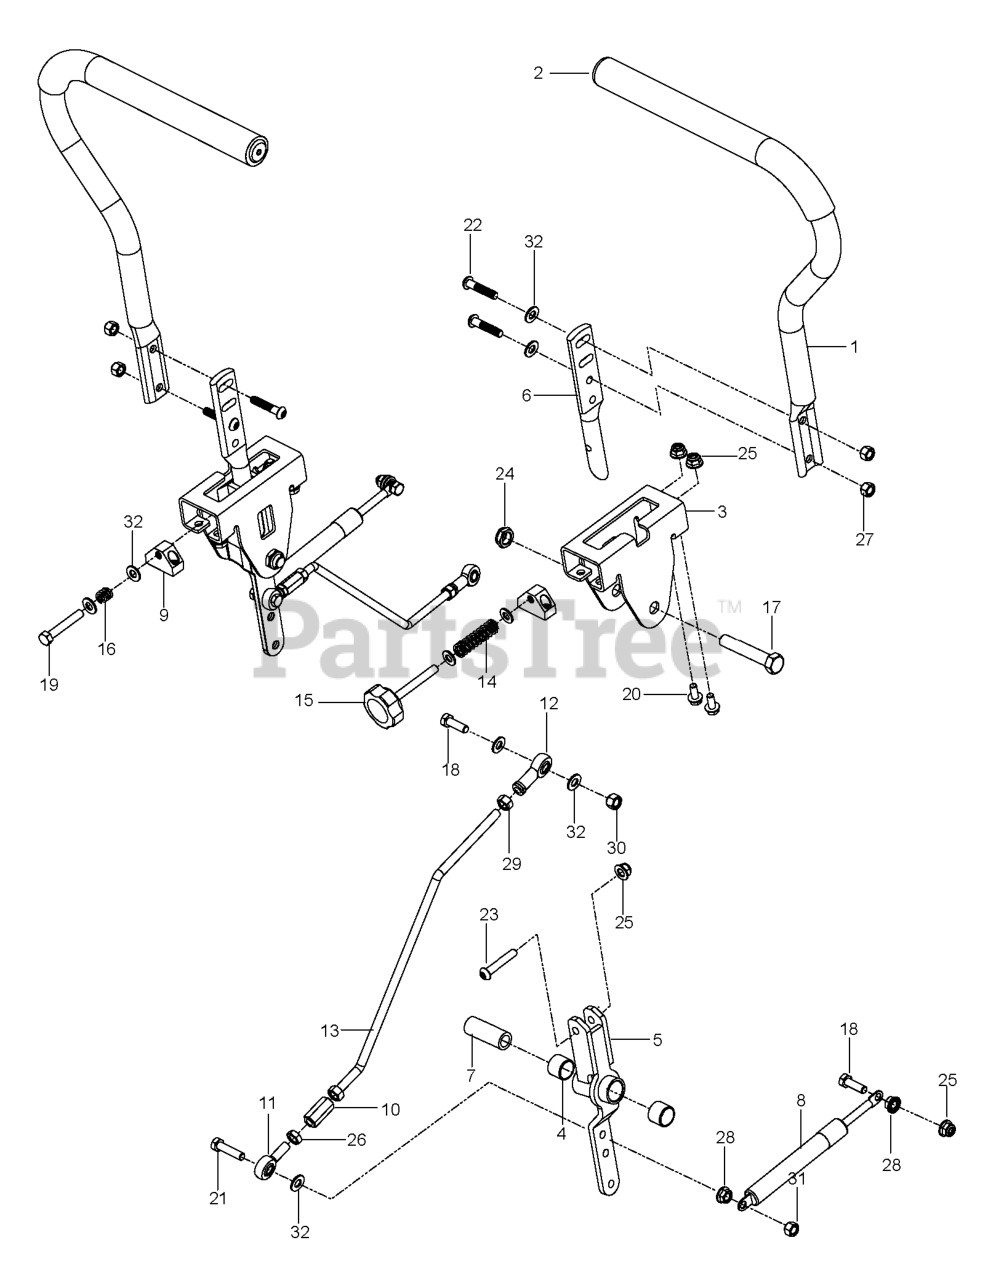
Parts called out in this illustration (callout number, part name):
1	LEVER ASSEMBLY
2	GRIP, FOAM (GROUND) 15
3	END PLUG 15/16 (BLACK)
4	BRACKET, CONTROL
5	BEARING, FLANGE
6	LEVER CONTROL PIVOT
7	LEVER.HANDLE MOUNT
8	SPACER, PIVOT CONTROL
10	BLOCK.TRACKING
12	SPRING COMPRESSION 2.0
14	ROD, MOTION CONTROL
15	RH ROD END
16	RP.ROD.END.LH
17	ROD END COUPLER
18	HCS 1/2C X 2 3/4
19	HCS 5/16C X 1
20	CAPSCREW 5/16 X 1/1/2 HEX HEAD
21	HHFS 5/16-18 X 3/4
22	HCS 5/16C X 1 3/4
23	SCREW BUTTONHEAD 5/16-18X1-1/2
23	SCREW 5/16-18 X 1 3/4 BTN-HD
24	NUT 1/2-13 HEX JM NYL
25	5/16-18 NYLOC FLANGE NUT
26	NUT 5/16F LEFTHAND
27	NYLOCK.NUT.5/16-18 BLACK
28	NUT 5/16C WHIZ
30	5/16-18 THIN PROF NY
31	NUT 5/16 NYLOC
32	WASHER
